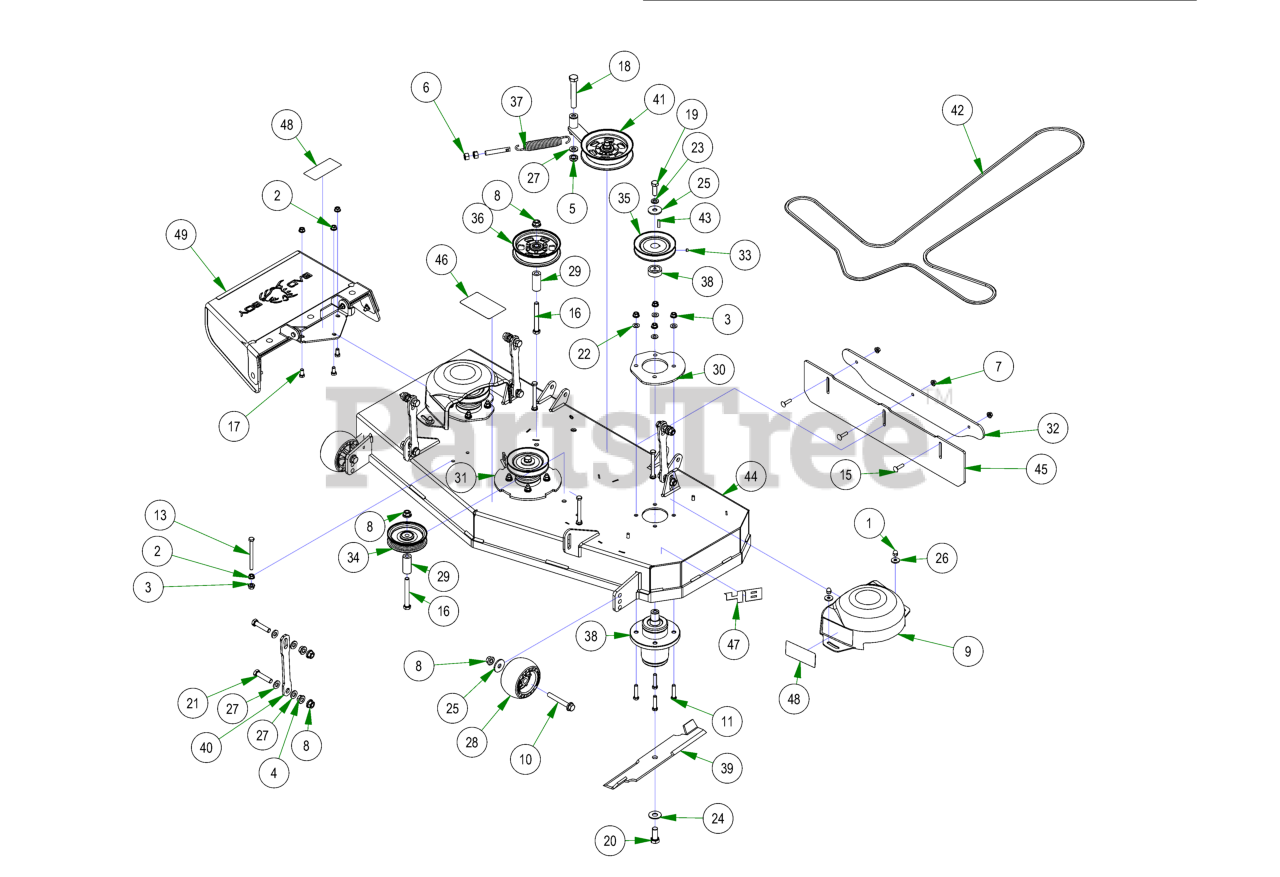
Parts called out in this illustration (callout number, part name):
1	5/16-18 ACORN NUT HIGH-CROWN ZC
2	3/8-16 HEX SERRATED FLANGE NUT HARD/ZINC
3	3/8-16 NYLON INSERT FLANGE LOCKNUT (GR.F) ZINC
4	1/2-13 HEX SERRATED FLANGE NUT HARD/ZINC
5	5/8-11 NYLON INSERT JAM LOCKNUT ZINC
6	1/2-13 HEX NUT ZINC
7	5/16-18 NYLON INSERT FLANGE LOCKNUT ZINC
8	1/2-13 NYLON INSERT FLANGE LOCKNUT ZINC
9	Pulley Cover
10	1/2-13 X 90MM HEX FLANGE BOLT W/SHOULDER (GR.8) ZINC
11	3/8-16 X 1-3/4 HEX C/S (GR.5) ZC
12	All Thread
13	3/8-16 X 4-1/4 HEX CAP SCREW (GR.5) ZINC
14	1/2-13 NYLON INSERT JAM LOCKNUT ZINC
15	5/16-18 X 1-1/4 CARRIAGE BOLT ZINC
16	1/2-13 X 4 HEX CAP SCREW (GR.8) ZINC YELLOW
17	3/8-16 X 3/4 HEX CAP SCREW (GR.5) ZINC
18	5/8-11 X 4 HEX CAP SCREW (GR.8) ZINC YELLOW
19	1/2"-20 x 1 1/2 - Grade 5 Fine Thread Bolt
20	5/8-18 X 1-1/2 HEX CAP SCREW (GR.8) ZINC YELLOW
21	1/2-13 X 2-1/4 HEX CAP SCREW (GR.5) ZINC
22	3/8 F/W SAE (13/16 OD) ZINC
23	1/2 SPLIT LOCKWASHER (GR.8) ZINC/YELLOW
24	5/8 USS FLAT WASHER (1-3/4" OD) GR.8 ZINC YELLOW
25	1/2 BELLEVILLE WASHER (1-5/8 OD X .140 THK) ZINC
26	.360 ID X .983 OD X .120 THICK FLAT WASHER NYLON BLACK
27	.505 ID X 1.000 OD X .125 THICK FLAT WASHER NYLON
28	Deck Wheel
29	2019 Revolt Stationary Idle Spacer
30	42&48 Deck Spindle Support Plate
31	Deck Spindle Support Plate
32	Striping Kit Plate
33	5/16-24 X 1/4 SOCKET SET SCREW (CUP PT) PLAIN
34	4 3/4" Idler Pulley
35	5" Spindle Deck Pulley
36	5-3/4 Idler Pulley
37	Deck Idler Spring
38	OUTLAW SPINDLE ASSEMBLY
39	48" ZT/Mav/Compact Outlaw Blade with Fusion
40	23WB Deck Hanger
41	2019 Revolt Deck Idler Assembly
42	42 inch Deck Belt- B120
43	1/4 X 1 SQ MACHINERY KEY 1018 STL PLN
44	23WB 48in Deck
45	2023 MZ Stripping Kit Rubber
46	2017 MZ Magnum 48"/42" Deck Route Decal
47	48" Deck Decal
48	Danger Decal-Spindle/Discharge
49	ZT Chute Assembly
